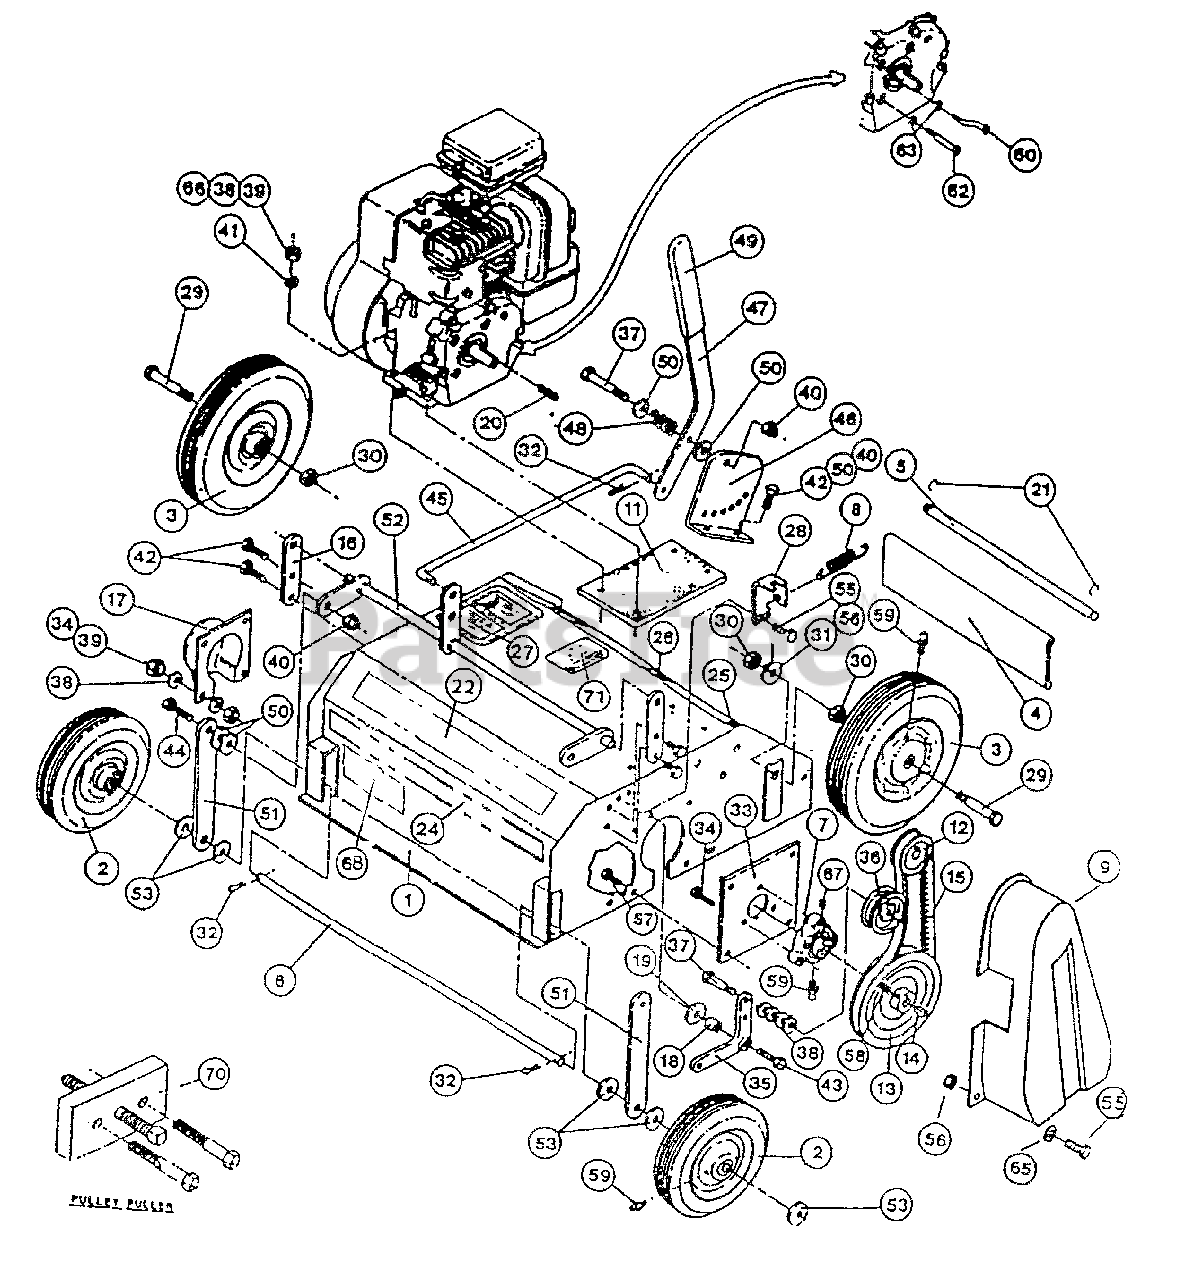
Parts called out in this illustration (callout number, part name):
1	Dethatcher Body w/Decals
1	Slicer Body w/Decals
2	Front Wheel
3	Rear Wheel
4	Deflector Shield
5	Deflector Rod
6	Front Axle
7	Flanged Bearing
8	Extension Spring
9	Belt Guard
11	Engine Pad
12	Engine Drive Pulley
13	Main Shaft Pulley
14	#9 Woodruff Key
15	Drive Belt
17	Shaft Guard
18	Oilite Bearing
20	3/16 Square x 1-3/4 Key
21	5/16 Retaining Ring
22	Decal, Husqvarna
24	Decal, DT20
25	Warning Decal, Small
26	Warning Decal, Large
27	Adjusting Decal
28	Cable Bracket
29	5/8-11 x 4 Axle Bolt
30	5/8-11 Hex Jam Nut
31	5/8 Split Lock Washer
32	1/8 x 3/4 Cotter Pin
34	5/16-18 x 1-1/4 Tap Bolt
35	Bell Crank
36	Idler Pulley
37	3/8-16 x 2 Hex Cap Screw
38	5/16 Flat Washer
39	5/16-18 Nyloc Nut
40	3/8-16 Nyloc Nut
41	5/16 Split Lock Washer
42	3/8-16 x 1 Hex Cap Screw
43	3/8-16 x 1-1/2 HCS
44	3/8-16 x 1-1/4 HCS
45	Linkage Arm
46	Adjustment Gauge
47	Adjusting Lever
48	Compression Spring
49	Lever Grip
50	3/8 Flat Washer
52	Height Adjusting Rod
53	1/2 Flat Washer
55	1/4-20 x 5/8 Hex Cap Screw
56	1/4-20 Nyloc Nut
57	5/16-18 x 3/4 Hex Cap Screw
58	5/16-18 x 3/8 Set Screw
59	1/4-28 Straight Grease Zerk
60	Belt Guide, Offset
62	5/16-24 x 2-3/4 HCS
63	5/16-24 Hex Jam Nut
65	1/4 Flat Washer
66	5/16-18 x 1-3/4 HCS
67	#10-32 x 1/4 Set Screw
68	Decal, Nascar
70	Pulley Puller
71	Decal, Warning
